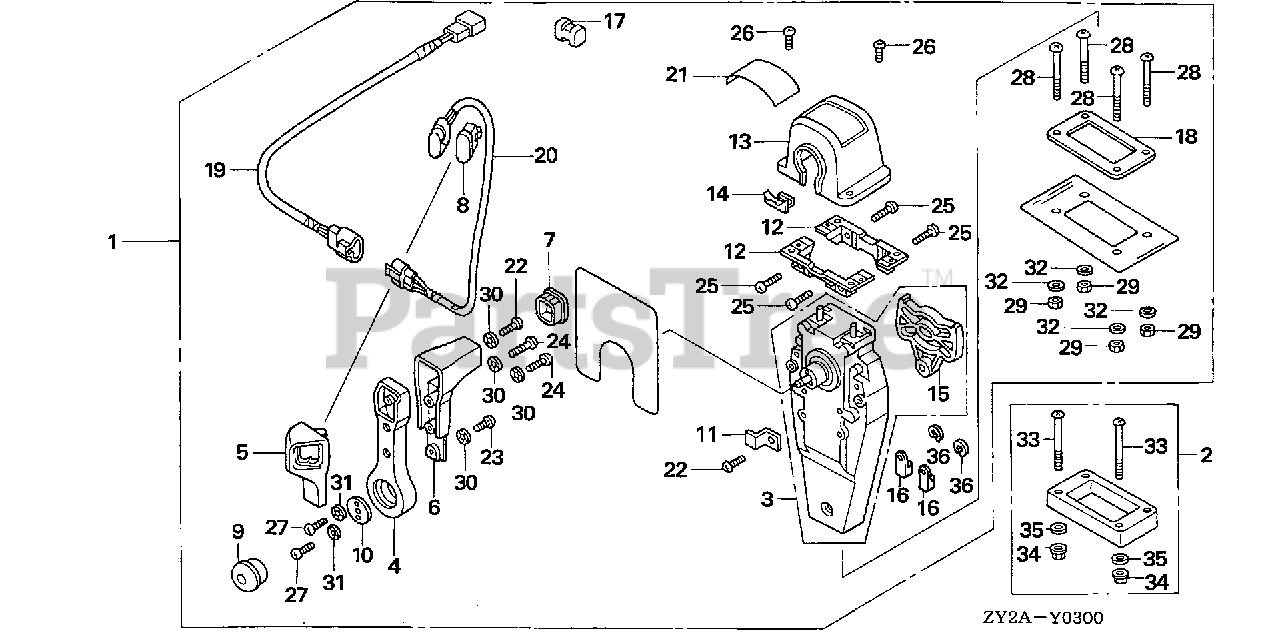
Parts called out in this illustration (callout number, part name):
1	BOX KIT, REMOTE CONTROL (TOP MOUNT SINGLE)(R)
2	SPACER KIT, REMOTE CONTROL BOX (TOP MOUNT SINGLE)
3	HOUSING ASSY., L. (INNER) (TOP MOUNT)
4	HANDLE, REMOTE CONTROL
5	COVER, L. GRIP
6	GRIP, REMOTE CONTROL HANDLE
7	CAP, GRIP
8	CAP, SWITCH
9	BUTTON, THROTTLE
10	PLATE, HANDLE
11	PLATE, CABLE CLAMP
12	BRACKET, REMOTE CONTROL HOUSING
13	HOUSING, REMOTE CONTROL BOX
14	HOUSING, LEAD
15	PLATE, DWELL
16	TERMINAL, CABLE
17	SPACER, CABLE CLAMP
18	GASKET, SINGLE
19	SUB-HARNESS ASSY., POWER TRIM-TILT (A)
20	SWITCH ASSY., POWER TRIM-TILT (A)
21	MARK, REMOTE CONTROL (SINGLE)
22	SCREW, PAN (5X16)
23	SCREW, PAN (5X10)
24	SCREW, PAN (5X20)
25	SCREW, PAN (5X18)
26	SCREW, PAN (4X10)
27	SCREW, PAN (6X18)
28	SCREW, PAN (5X40)
29	NUT, HEX. (5MM)
30	WASHER, LOCK (5MM)
31	WASHER, LOCK (6MM)
32	WASHER, PLAIN (5MM)
33	SCREW, PAN (5X65)
34	NUT, HEX. (5MM)
35	WASHER, PLAIN (5MM)
36	E-RING (6MM)
